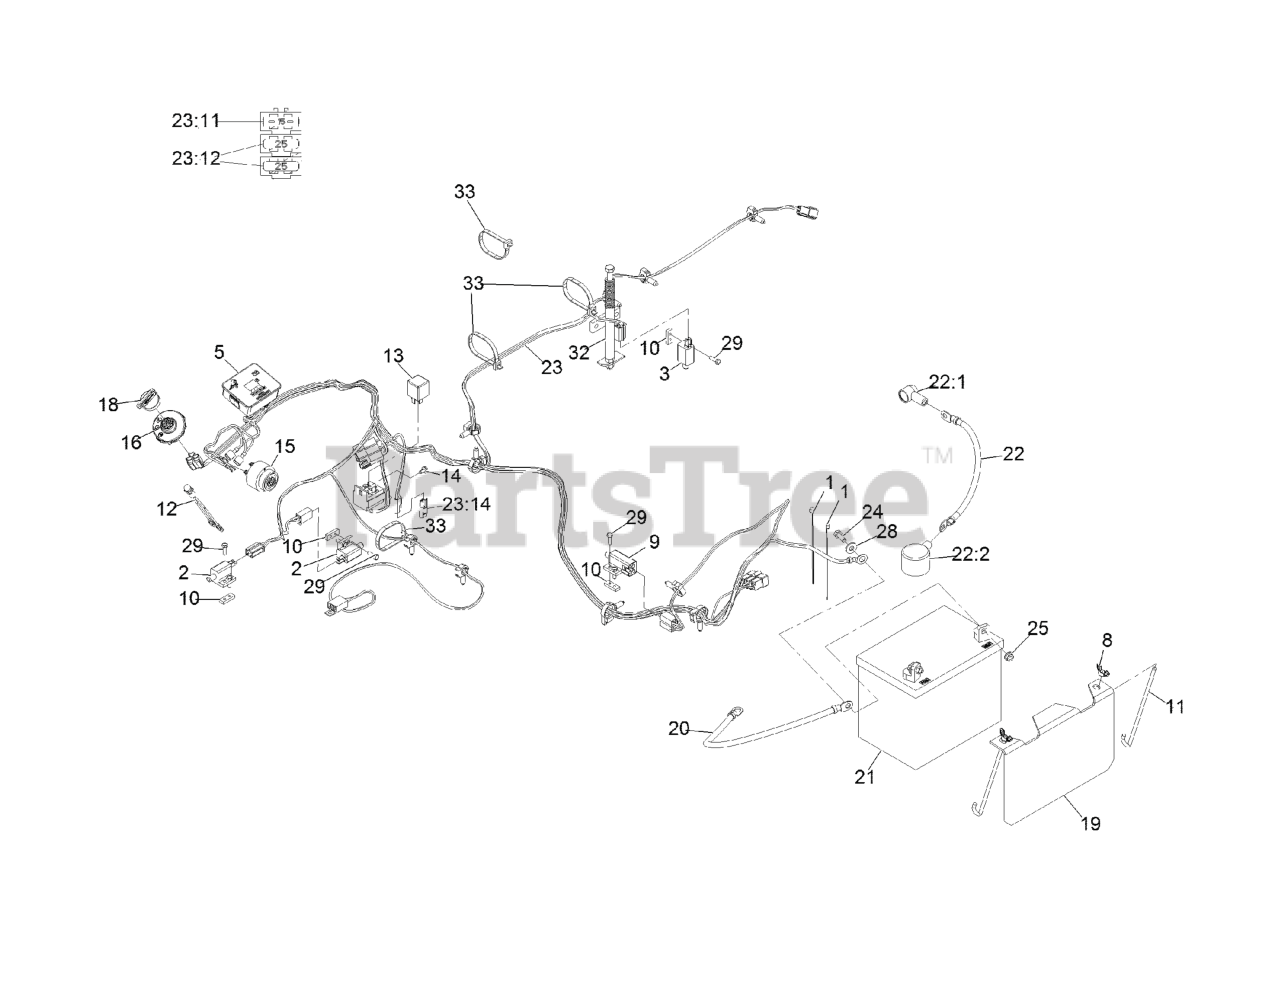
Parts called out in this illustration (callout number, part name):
1	TIE-CABLE
2	SWITCH-OPEN, NORMALLY
3	SWITCH-CLOSED, NORMALLY
5	HOUR METER ASM
8	WINGNUT
10	PLATE-TAPPED
11	BOLT-HOLDDOWN
12	INDICATOR-LED, RED
14	SCREW-HWH
15	ALARM-TONE, DUAL
16	SWITCH-IGNITION
18	KEY-IGNITION
19	HOLD DOWN-BATTERY
20	CABLE-BATTERY, NEGATIVE
21	Battery
22	CABLE-BATTERY, POSITIVE
22:1	INSULATOR-SOLENOID
22:2	INSULATOR-BATTERY
23	HARNESS-WIRING
23:11	FUSE-BLADE, 15 AMP
23:12	FUSE-BLADE, 25 AMP
23:14	CAP-PLUG
24	SCREW-HH
28	WASHER-FLAT
32	HOPPER SWITCH ACTUATOR AS
33	TIE-PLASTIC
